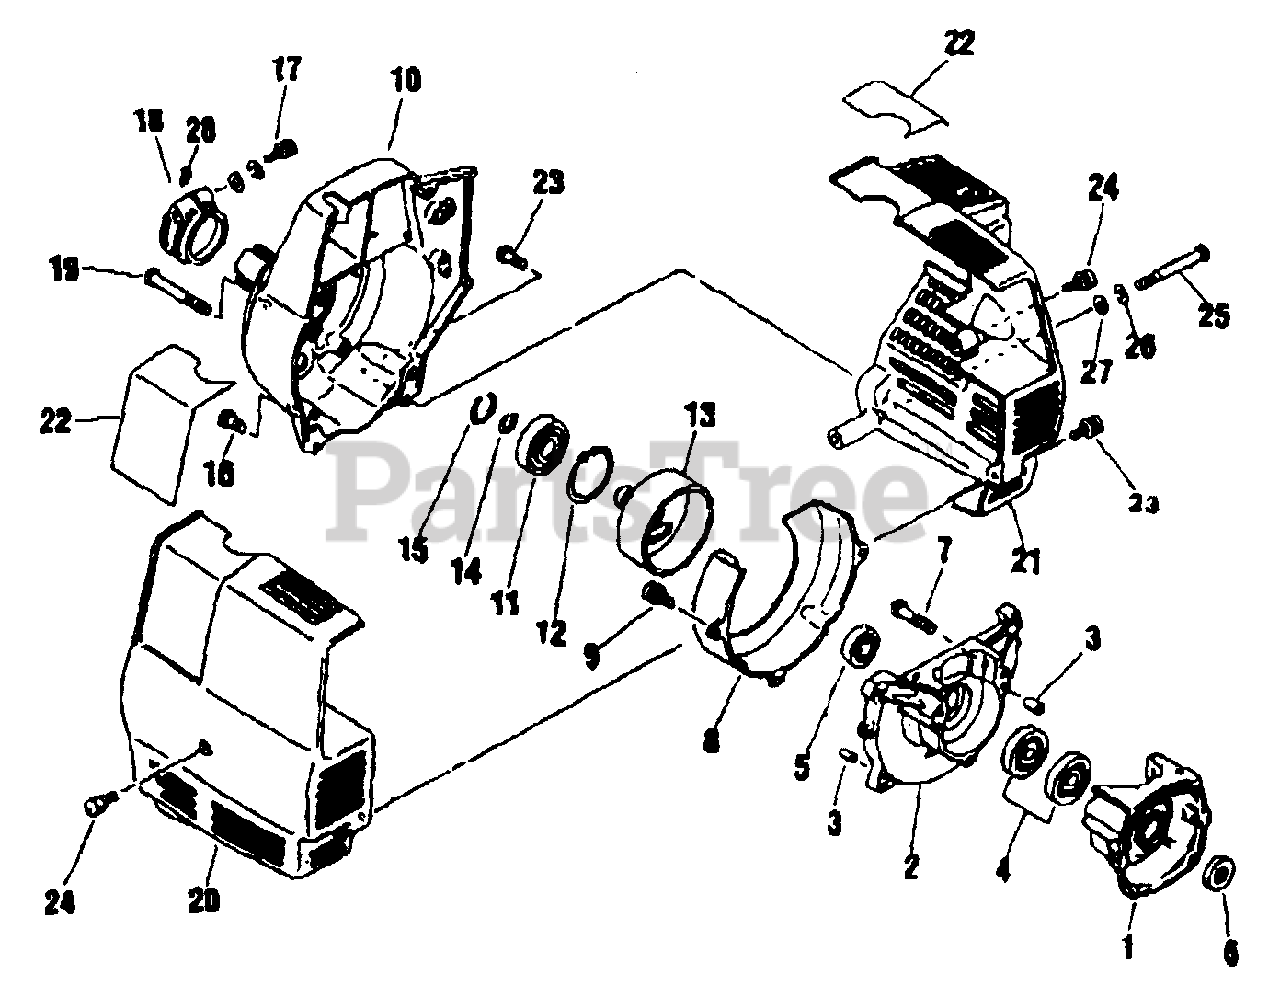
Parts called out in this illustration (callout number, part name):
1	CRANKCASE - REAR
2	CRANKCASE - FRONT
3	PIN - LOCATING
4	BEARING, BALL - 6001
5	SEAL, OIL - 12
6	SEAL, OIL
7	SCREW - 5X25
8	DEFLECTOR, AIR
9	SCREW - 4X12
10	CASE, FAN
11	BEARING, BALL - 6201
12	RING, RETAINING - 32
13	DRUM, CLUTCH
14	RING, RETAINING
15	RING, RETAINING
16	SCREW - 5X16
17	SCREW - 5X25
18	CLAMP
19	SCREW - 5X50
20	COVER, ENGINE - LEFT
21	COVER, ENGINE - RIGHT
22	NAME PLATE
23	SCREW - 5X16
24	SCREW - 5X25
25	SCREW - 5X50
26	LOCKWASHER - 5
27	WASHER - 5
28	SHIM
